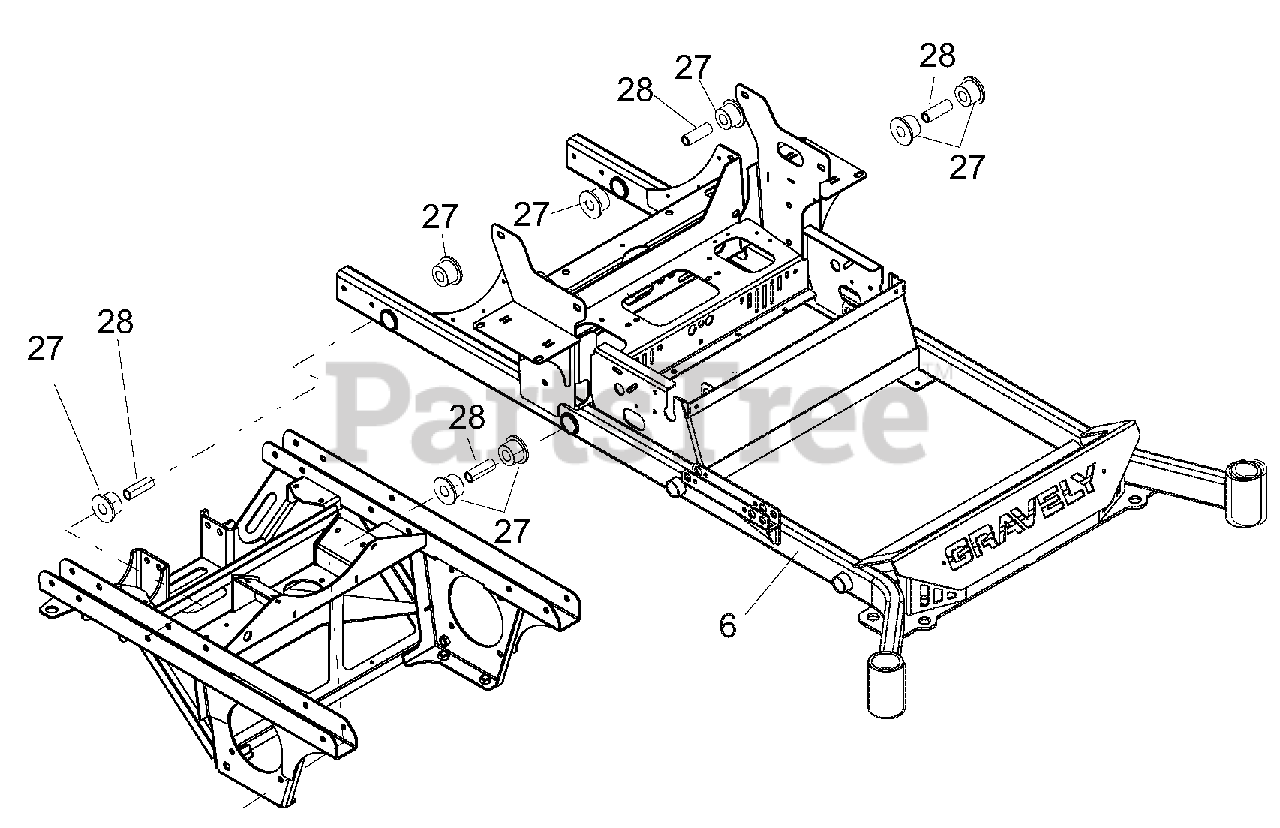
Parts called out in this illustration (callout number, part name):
6	WLDMT, PT400 MAIN FRAME (992236)
27	BUSHING, FLANGE .75X1.51X1.13X2.0 URE
28	BUSHING, SHEAVE .50X.75X2.23
